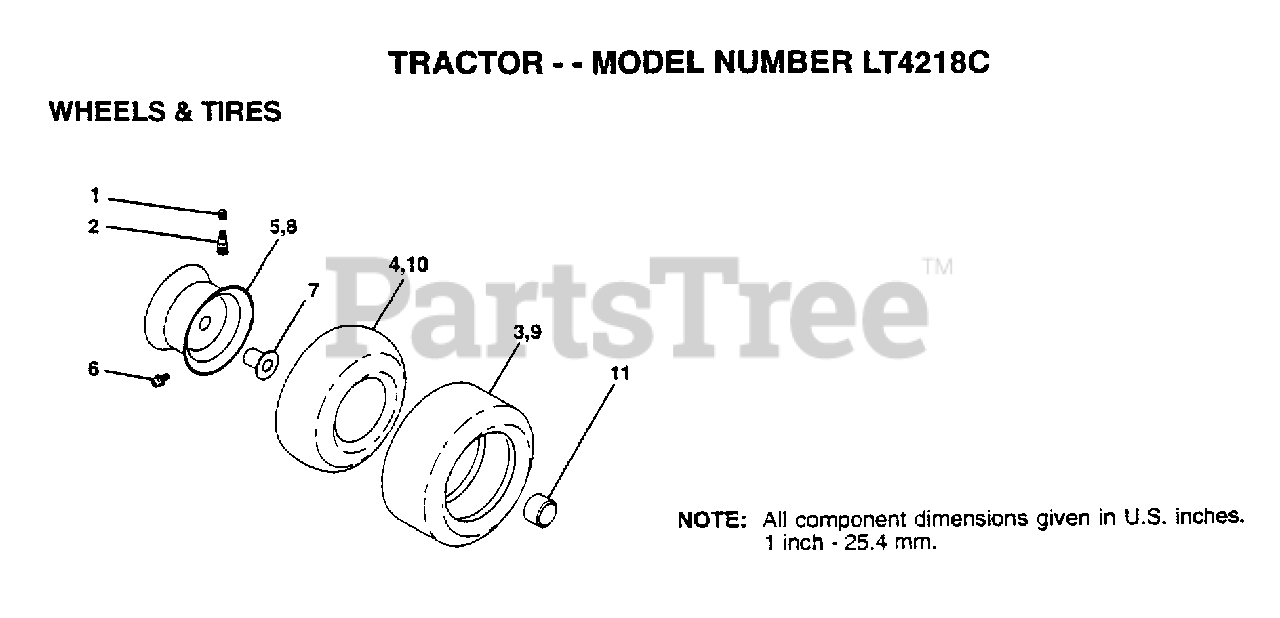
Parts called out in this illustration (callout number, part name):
1	VALVE CAP
2	VALVE STEM LT
4	TUBE.5.3/4.5/6
5	"RIM FRT 6"" ASM"
6	FITTING LT
7	"FLANGE, BEARING"
8	"RIM REAR 8"" ASM"
9	TIRE.20X8-8
10	TUBE.18X9.5-8
11	HUB CAP
